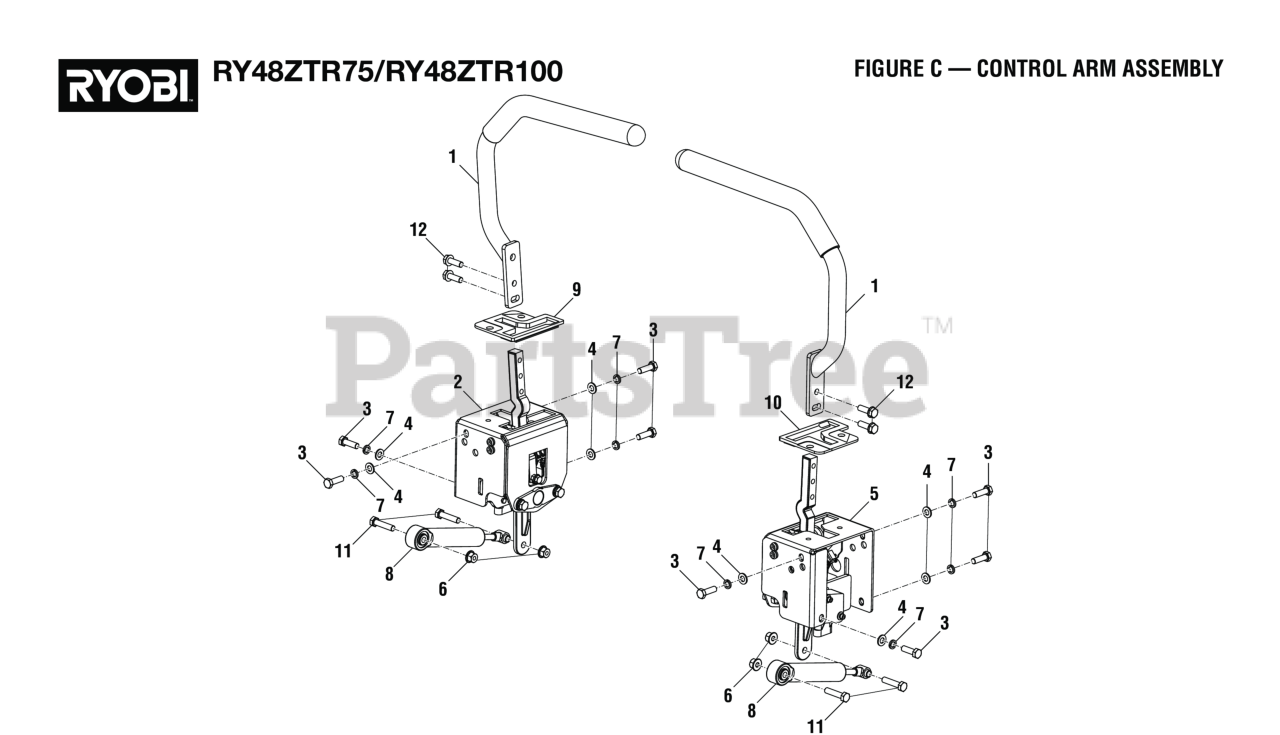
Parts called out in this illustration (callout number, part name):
1	Control Arm Handle
2	Control Arm Assembly, Left
3	Bolt (M8 x 25 mm, Hex Hd.)
4	Washer (OD16 x ID8.4 x 1.6t)
5	Control Arm Assembly, Right
6	Flange Nut (M8) (For Drive Motor Controller V)
7	Lock Washer (OD9.8 x ID8.5 x 5t)
8	Control Arm Damper
9	T Slot Insert, Left
10	T Slot Insert, Right
11	Bolt (M8 x 35 mm, Hex Hd.)
12	Bolt w/Washer (M8 x 25 mm, Hex Hd.)
